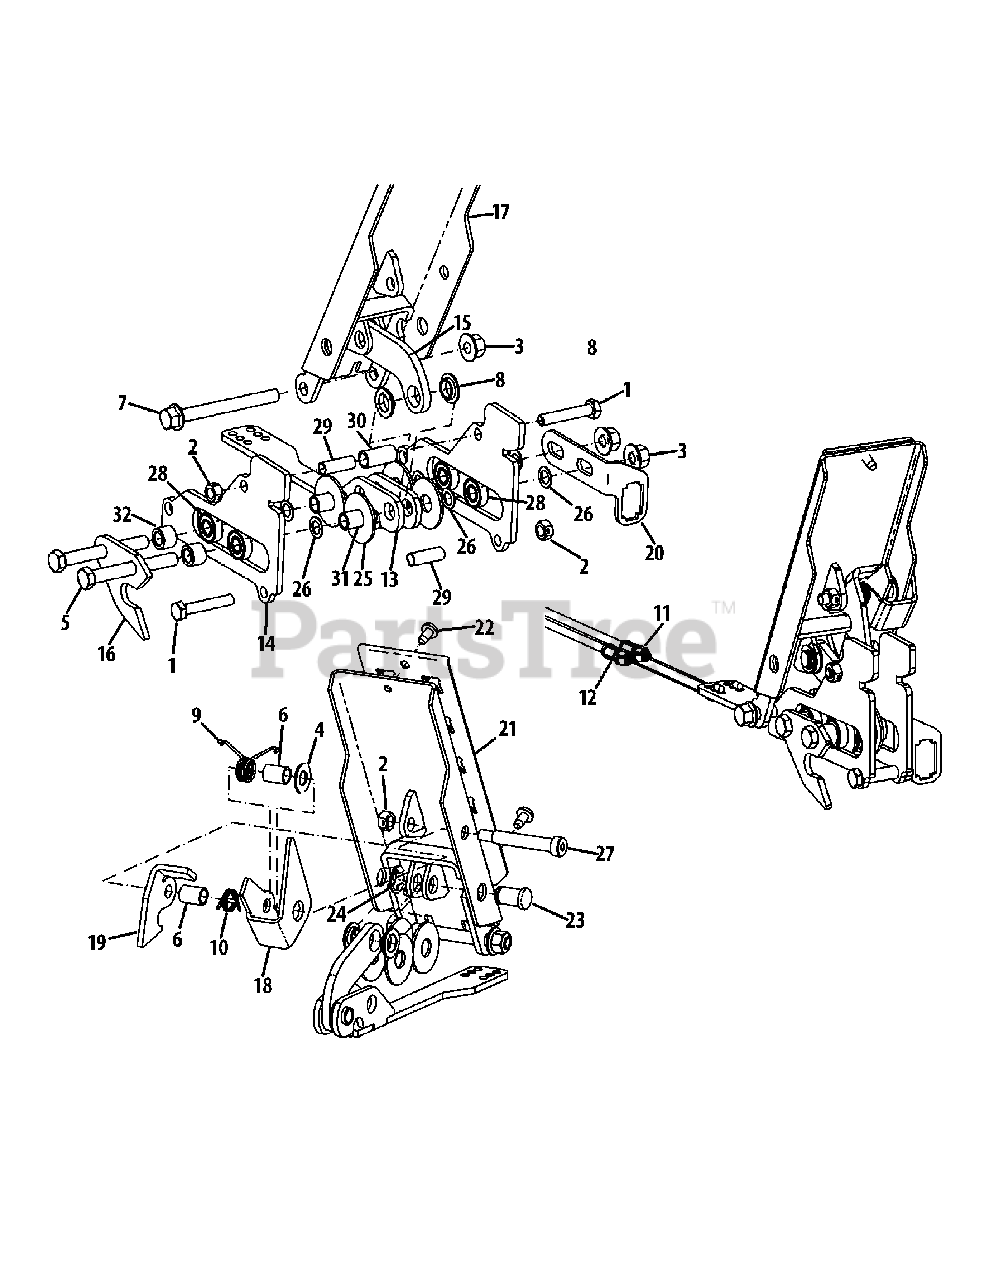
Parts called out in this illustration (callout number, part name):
1	Hex Screw, 5/16-18 x 1.75
2	Counter Lock Nut, 5/16-18
3	Flange Counter Lock Nut, 3/8-16
4	Washer, .416 x .875 x .046
5	Hex Screw, 3/8-16 x 3.00
6	Spacer, .380 x .500 x .667
7	Hex Screw, 3/8-16 x 3.50
8	Flange Bearing, .502 x .875 x .180
9	Torsion Spring
10	Torsion Spring
11	LH Brake Cable
12	RH Brake Cable
13	Brake Carrier Assembly
14	Brake Roller Guide Bracket
15	Brake Control Link
16	Lockout Plate
19	Brake Hook Bracket
23	Pin, .500 x .804
25	Flat Washer, .531 x 1.5 x .08
26	Washer, .39 x .62 x .03
27	Shoulder Screw, 5/16-18 x .375 x 2.00
28	Bearing, .375 x .875
29	Spacer, .319 x .375 x 1.056
30	Spacer, .384 x .500 x 1.000
31	Spacer, .38 x .5 x .955
32	Spacer, .385 x .625 x .458
